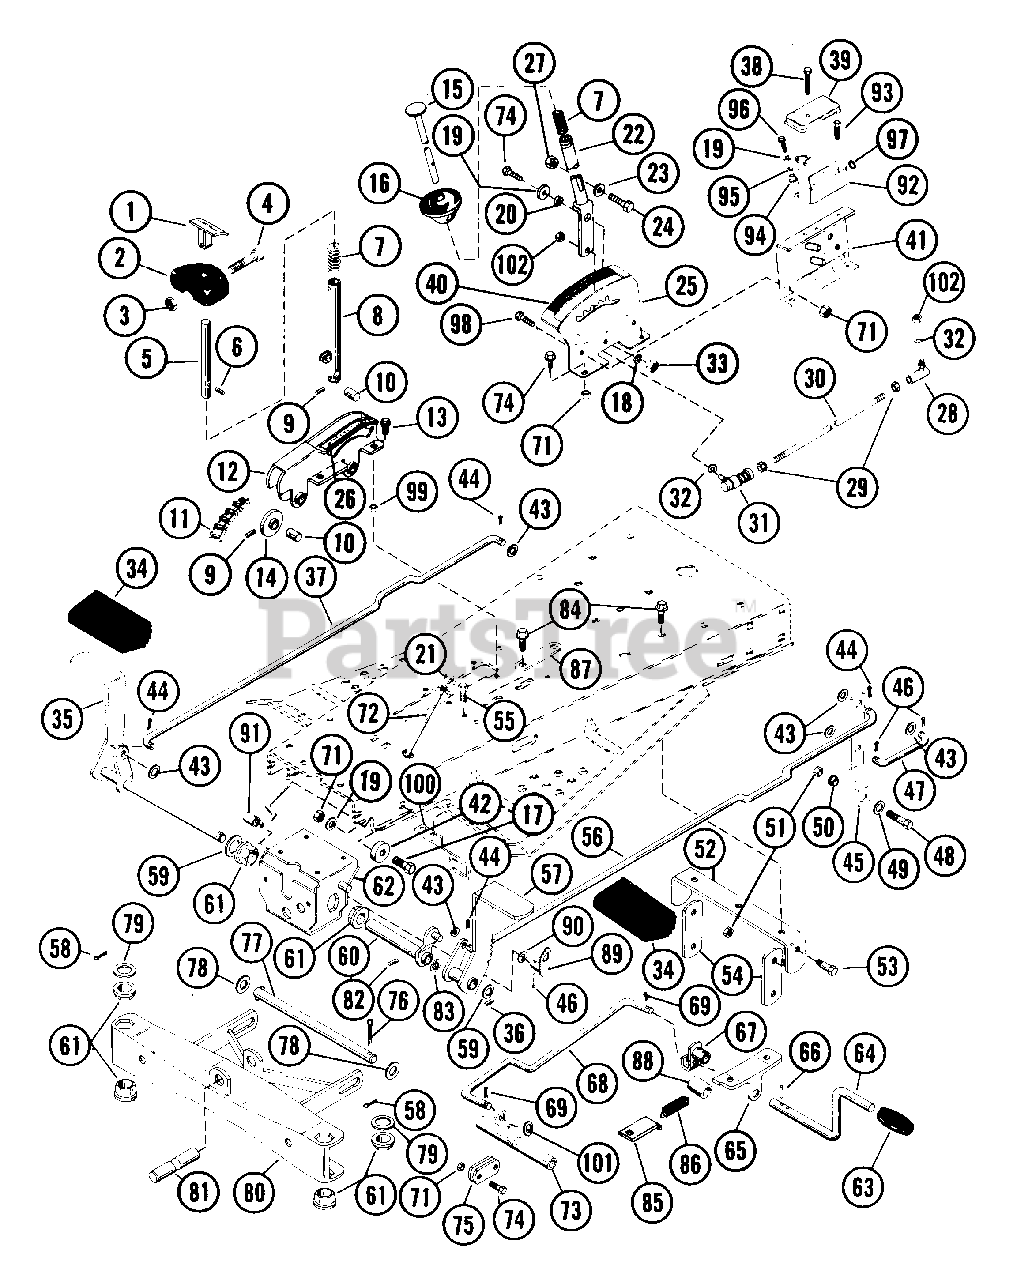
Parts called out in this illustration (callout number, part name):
1	T PLUNGER
2	T HANDLE
3	NUT-LK TOP 10-24 PL
4	BLT-HEX 10-24X1.25 FHPL
6	PIN-ROLL .250X1.25
7	SG-COMP ??X.44X?? WLD 10
8	MOWER LIFT ARM
9	PIN-ROLL .125X.75
11	ROLLER CHAIN
12	MOWER HEIGHT QUADRANT
13	BLT-HEX .25-20X.50 PL GR2
14	CHAIN ROLLER
15	SHIFT RELEASE HANDLE
16	SHIFT BALL
17	BLT-HEX .31-18X1.00 PL GR 2
18	WSHR-LK .312X.097 PL HVY
19	WSHR-FL-STL .38X.875X.083 PL
20	SPACER BUSHING .5 X .32 X .21
22	SHIFT LEVER
23	WSHR-FL-STL .281X1.250X.048PL
24	BLT-HEX .25-20X1.25
25	SHIFT CONTROL SEGMENT
26	HEIGHT QUADRANT LABEL
27	NUT-LK TOP .250-20 PL
28	BALL JOINT
29	NUT-HEX .312-24 PL
30	SHIFT LINK
31	SNAP IN BALL JOINT
32	WSHR-LK .312X.097 PL HVY
33	NUT-HEX .312-18
34	PEDAL COVER
35	BRAKE LEVER
36	PIN-ROLL .125X1.00
37	BRAKE ROD
38	SCR-TAP 12-14X1.25 CROVH PL 1A
40	MOWER SHIFT LABEL
41	SWITCH BRACKET
42	SPACER .344X1.000X.375
43	WSHR-FL-STL .382X.812X.023 PL
44	PIN-COTR .09X.75 PL
45	CLUTCH LINK BAR
46	PIN-COTR .12X1.0 PL
47	CLUTCH LINKAGE ROD
48	BLT-HEX .38-16X.75 PL GR2
49	WSHR-FL-STL .630X1.005X.062 PL
50	SHOULDER SPACER
51	NUT-LK-CTR .375-16 GR A PL
52	HANGER BRACKET
53	SHOULDER BOLT
54	HANGER LINK
55	BLT-SERHFWH .25-20X.50 PL
56	CLUTCH ROD
57	CLUTCH BRAKE LEVER
58	PIN-COTR .12 X 1.25 PL
59	WSHR-FL-STL .505X.875X.024 PL
60	CLUTCH BRAKE LEVER
61	FLANGE BUSHING
62	AXLE SUPPORT
64	MOWER CLUTCH PEDAL
65	MOWER CLUTCH BRACKET
66	PIN-ROLL .188X1.00
67	OVER CENTER LEVER
68	MOWER CLUTCH LINK
69	PIN-COTR .09X.75 PL
71	NUT-LK .312-18 GR A PL
72	PARKING BRAKE ROD
73	MOWER CLUTCH LEVER
74	BLT-HEX .31-18X.75 PL GR2
75	FRONT LINK
76	PIN-COTR .12X1.0 PL
77	HANGER PIN
78	WSHR-FL-STL .531X1.062X.095 PL
79	WSHR-FL-STL .755X1.375X.062 PL
80	FRONT AXLE
81	AXLE PIVOT PIN
82	PIN-ROLL .188X.88
83	WAVE WASHER .531X.781X.125FH
84	BLT-SCRHFWH .38-16X.50 PL
85	SPRING CLIP
86	SG-TENS .062X.437X.312 WLD 12
87	GUIDE PLATE
89	BRAKE LATCH
90	WSHR-FL-STL .511X1.441X.125 PL
91	BRAKE RELEASE LEVER
92	SWITCH HOUSING
93	SCR-TAP 10-24X.375 CRPH 1A
94	BSHG, FLG .325X.499X.26X.88
95	CAM NO SCRAP
96	BLT-SERHFWH .31-18X.75 PL
97	GROMMET, .31 ID
98	BLT-HEX .31-18X.50 PL GR2
99	NUT-LK-CTR .250-20 PL
100	SWITCH BRACKET
101	WSHR-FL-STL .380X.626X.033
102	NUT-LK .312-24
